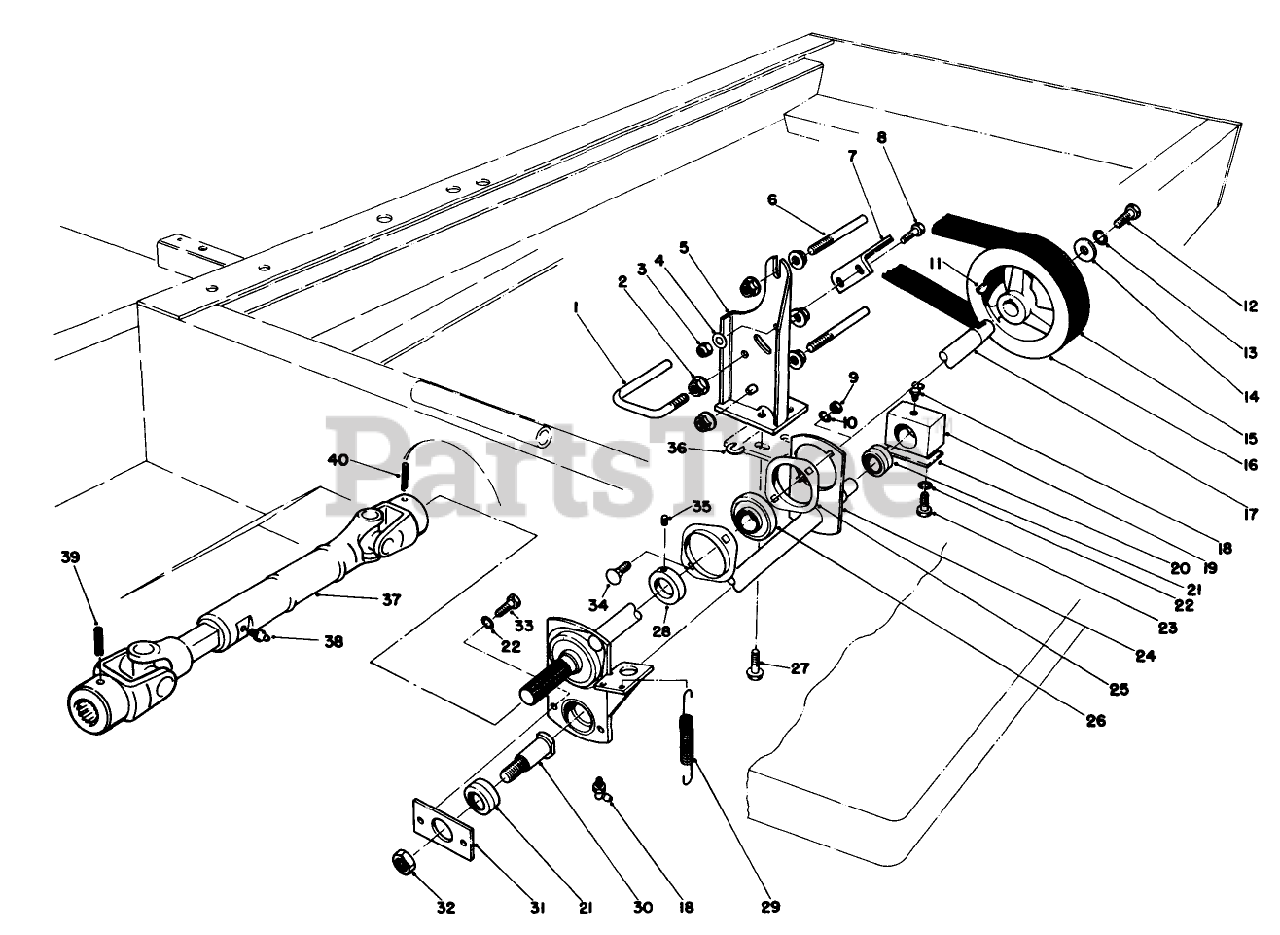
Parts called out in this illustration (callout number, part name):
1	LOWER BELT GUIDE
2	NUT-HHF, WHIZ
3	NUT-LOCK, NI
4	WASHER-PLAIN
5	Bracket-Brake
6	UPPER BELT GUIDE
7	PTO SUPT PAD ASM
8	SCREW-HH
9	NUT-HEX
10	WASHER-LOCK
11	KEY-WOODRUFF
12	SCREW-HH
13	WASHER-LOCK
14	WASHER-FLAT
15	V-BELT
16	Pulley-PTO
17	PTO SHAFT
18	FITTING-GREASE, 90 DEG
19	BEARING HUB PP
20	PTO SHIM BLOCK
21	BEARING
22	WASHER-LOCK
23	SCREW-HH
24	ARM WA - ENGAGE R
25	FLANGE
26	Bearing w/Collar (Incl. Ref. #28 & 35)
27	SCREW-HHF
28	COLLAR-LOCK, BEARING
29	TENSION PTO SPRING R
30	BEARING STUD
31	BRG RETAINER
32	NUT-LOCK, NI
33	SCREW-HH
34	SCREW-CARR
35	SCREW-SET, HSH
36	SPECIAL WASHER
37	UNIVERSAL JOINT
38	FITTING-GREASE
39	PIN-ROLL
40	ROLL PIN
